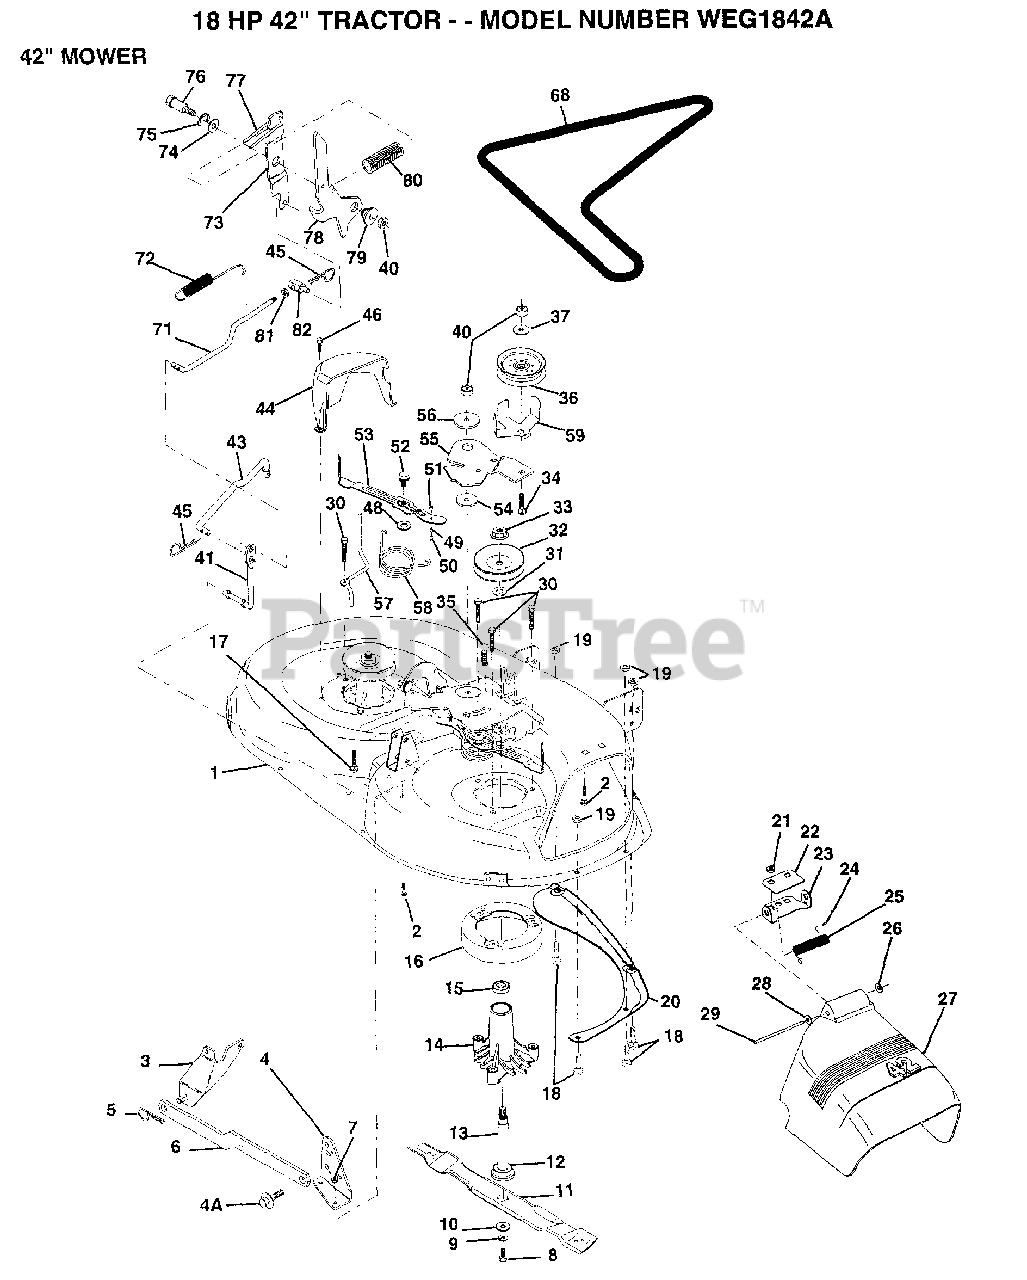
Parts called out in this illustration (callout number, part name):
2	BOLT
3	BRKT ASM SWAY BAR
4	BRKT DECK SW BAR
4A	BOLT SHD 5/16-18
7	NUT
8	BLADE BOLT
10	WASHER.HARD.BLADE
11	"BLADE.42"" MULCHER"
12	BEARING.BALL
14	HSG ASM MANDREL
15	BEARING
17	BOLT RDHD 3/8-16
18	BOLT
19	NUT
21	NUT
22	STIFFENER BRKT
23	DEFLECTOR BRKT
24	CAP-SLEEVE LT
25	SPRING TORSION
26	NUT PUSH M
27	DEFLECTOR.SHIELD
28	WASHER
29	HINGE ROD
31	WASHER
34	BOLT
35	XMAS TREE FASTNER
36	FLAT IDLER PULLEY
37	WASHER
40	NUT
41	PIVOT ROD
43	ROD CLUTCH W/NIBS
44	GUARD MAND LH BLK
45	RETAINER M
46	SCREW.1/4-20X5/8
48	HARD SMALL WASHER
50	SHOULDER BOLT
51	LOCKNUT
52	BOLT.SHLD.5/16-18
53	BRAKE PAD ARM ASM
54	HARDENED WASHER
56	SPACER RETAINER
57	KEEPER BELT LH 42
58	SPRING TORSN BRAK
59	GUARD IDLER TUV
68	BELT-V MWR 82.625
71	ROD CLUTCH 38/42
72	SPRING EXT
73	CLUTCH ARM SECOND
74	WASHER
75	RING
76	SHOULDER BOLT
77	SPRING KEEPER
79	BUSHING
81	NUT
82	TRUNION ADJ
